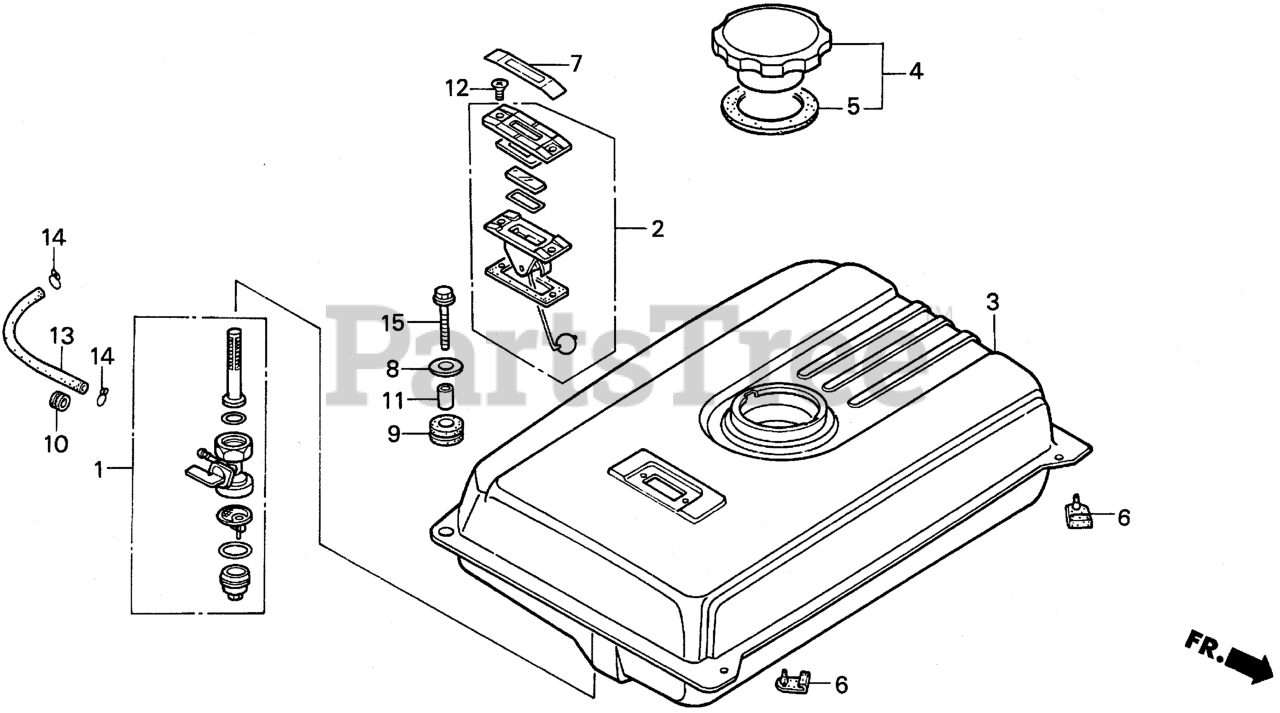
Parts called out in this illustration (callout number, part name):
1	PETCOCK ASSY.
2	METER ASSY., FUEL
3	TANK, FUEL *R280* (POWER RED)
4	CAP, FUEL FILLER
5	GASKET, FUEL FILLER CAP
6	RUBBER, TANK MOUNTING
7	MARK, FUEL METER
8	WASHER, TANK CUSHION
9	CUSHION, TANK RUBBER
10	RUBBER, FUEL (9X15X10)
11	COLLAR, TANK CUSHION
12	SCREW, FLAT (5X10)
13	BULK HOSE, FUEL (4.5X3000) (Honda Code 5137104). (4.5X140)
14	CLIP, TUBE (B8)
15	BOLT, FLANGE (6X22)
15	BOLT, FLANGE (6X25)
